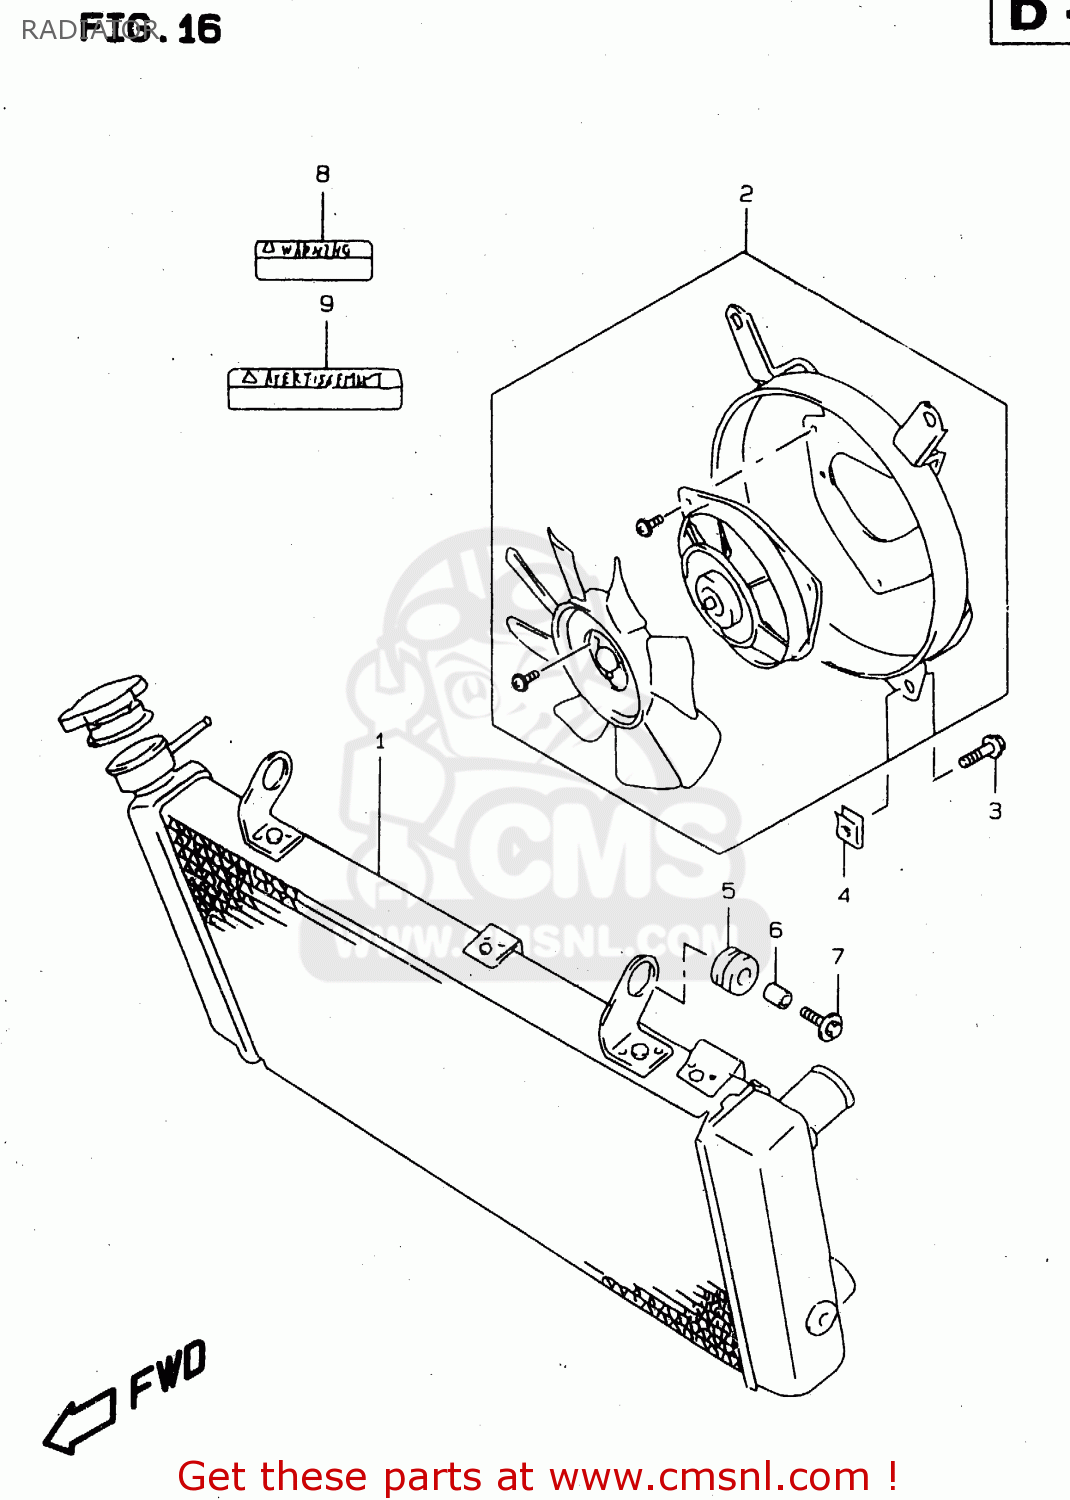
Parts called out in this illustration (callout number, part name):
1	RADIATOR ASSY,WATER
2	FAN ASSY,RADIATOR
3	BOLT
4	NUT
5	CUSHION
6	SPACER(6.5X10X12)
7	BOLT(6X25)
8	LABEL (COOLING FAN)
9	LABEL,COOLING FAN
